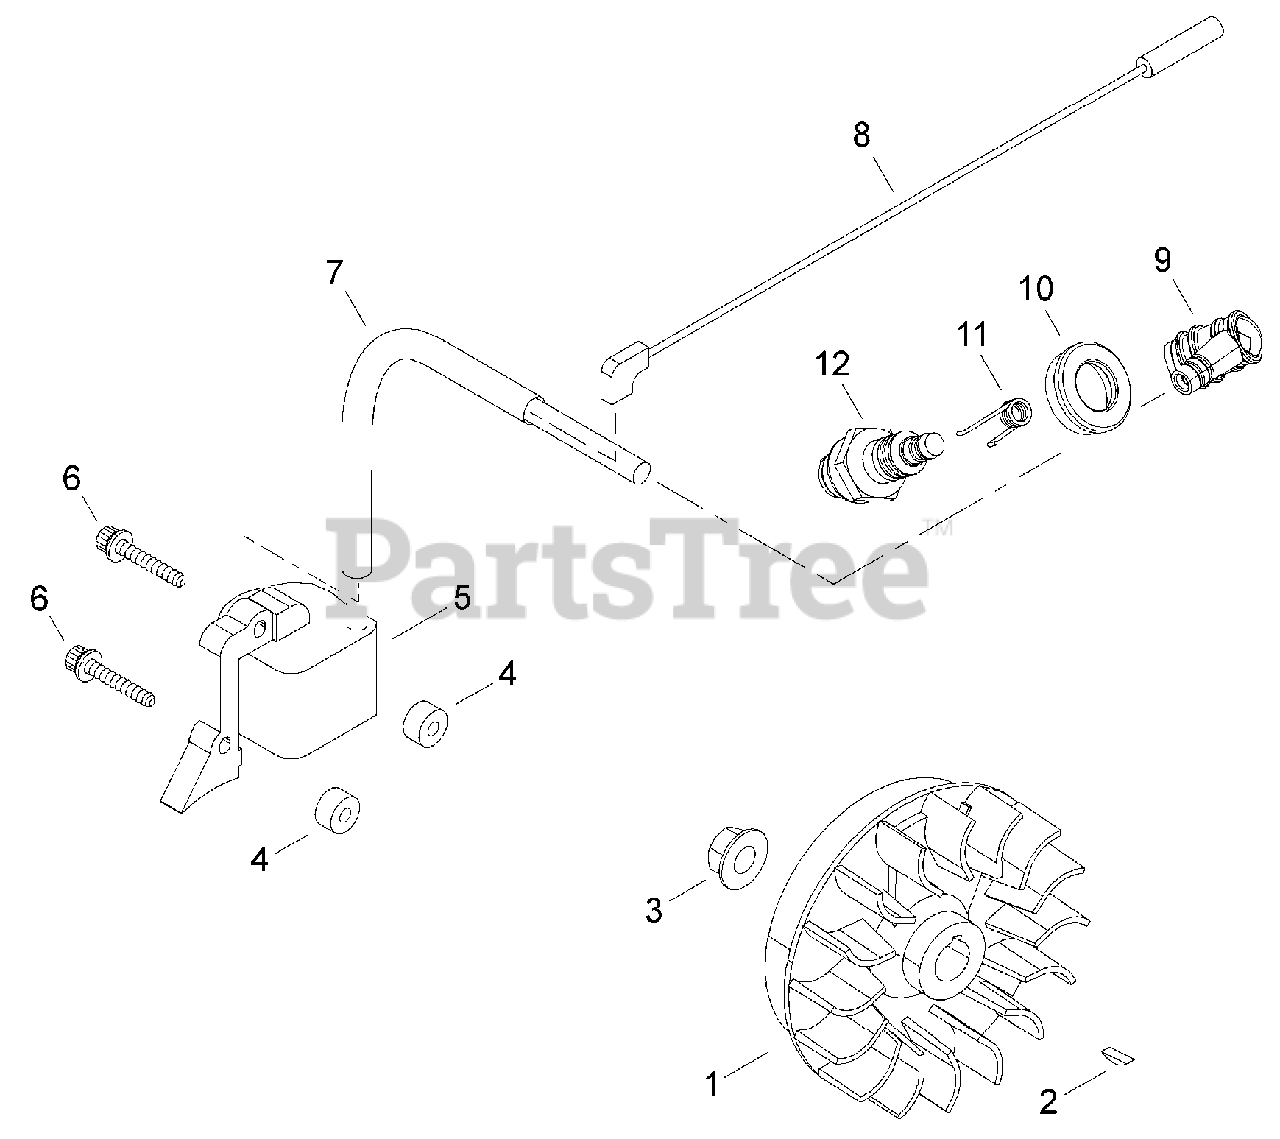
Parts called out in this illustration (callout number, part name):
2	KEY, WOODRUFF 3×10
3	NUT M8
4	INSULATOR 4.2×11×6
5	COIL, IGNITION
5-1	FLYWHEEL
6	BOLT, ADHESIVE M4×20
7	TUBE, IGNITION COIL
8	LEAD - IGNITION L= 215
9	CAP, SPARK PLUG
10	SEAL, SPARK PLUG
11	TERMINAL, SPARK PLUG
12	SPARK PLUG - BPMR6A
